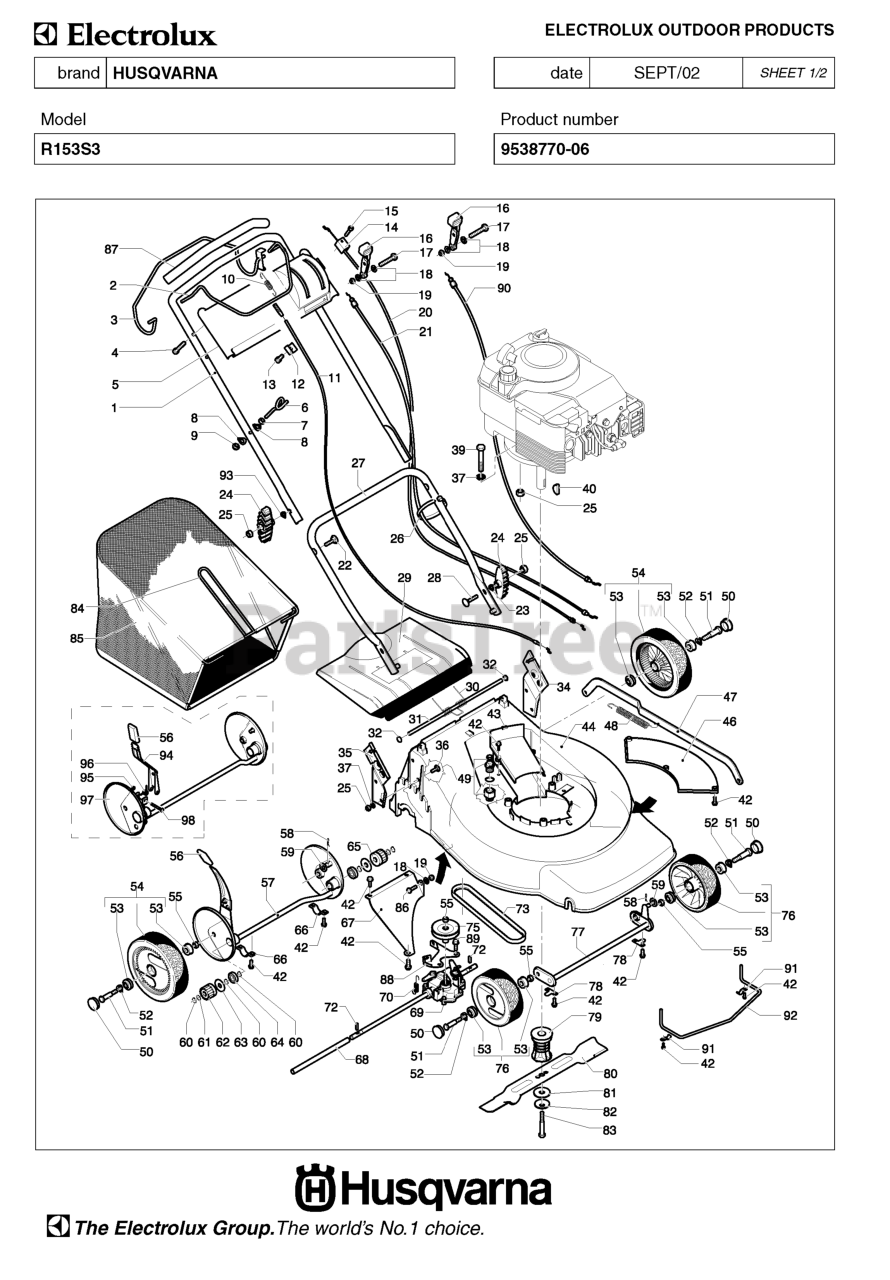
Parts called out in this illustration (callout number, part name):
28	Screws
42	Screws
58	Pins
60	Washers
